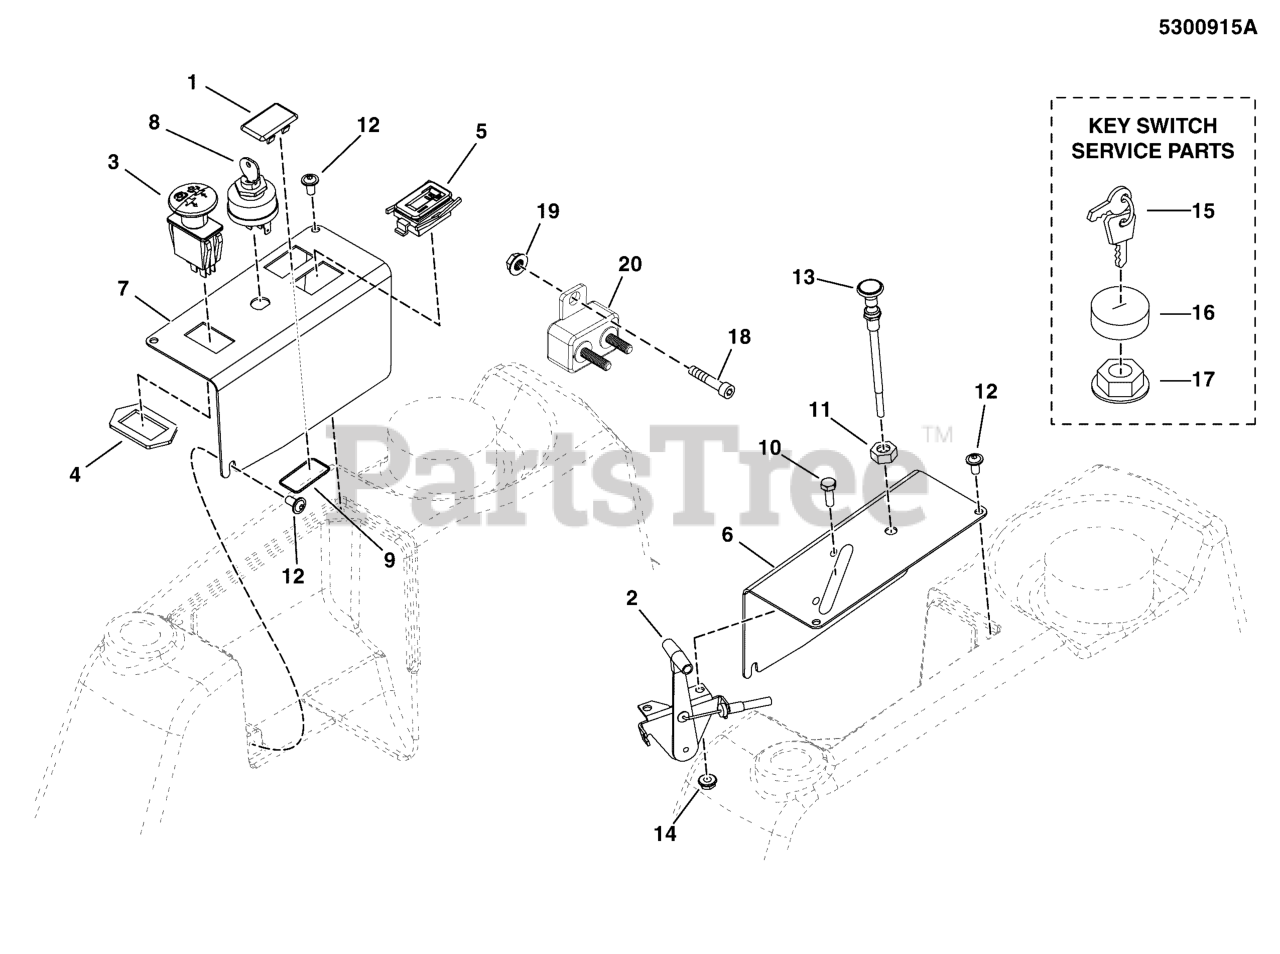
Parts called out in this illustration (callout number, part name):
1	PLUG, .820X1.44 HOLE, BLACK PLASTIC
2	CABLE, THROTTLE CONTROL, 48"
3	SWITCH, BLADE ENGAGEMENT
4	RING, SWITCH RETAINER
5	* HOUR METER, ASSEMBLY
6	CONTROL PANEL, LEFT - BLK
7	CONTROL PANEL, RIGHT - BLK
8	SWITCH, IGNITION, 6 POST
9	O-RING, 7/8 ID X 1/16 W
10	HHCS, 1/4-20 X 0.625, GR5, ZINC/CLEAR
11	NUT, 3/8-24 HEX JAM
12	SCREW, ALLEN HEAD 1/4-20X.500 ZINC PHOS
13	CABLE, CHOKE CONTROL, 51 (Z)
14	NUT, 1/4-20 HEX NYLOCK FLANGE
15	KEY, IGNITION MOLDED SET
16	COVER, PLASTIC, SNAP ON
17	PLASTIC NUT
18	SCREW, ALLEN HEAD 1/4-20X.500 ZINC PHOS
19	NUT, 1/4-20 HEX SERR. FLANGE
20	BREAKER-CIRCUIT 12VOLT 20AMPS W/TAB
